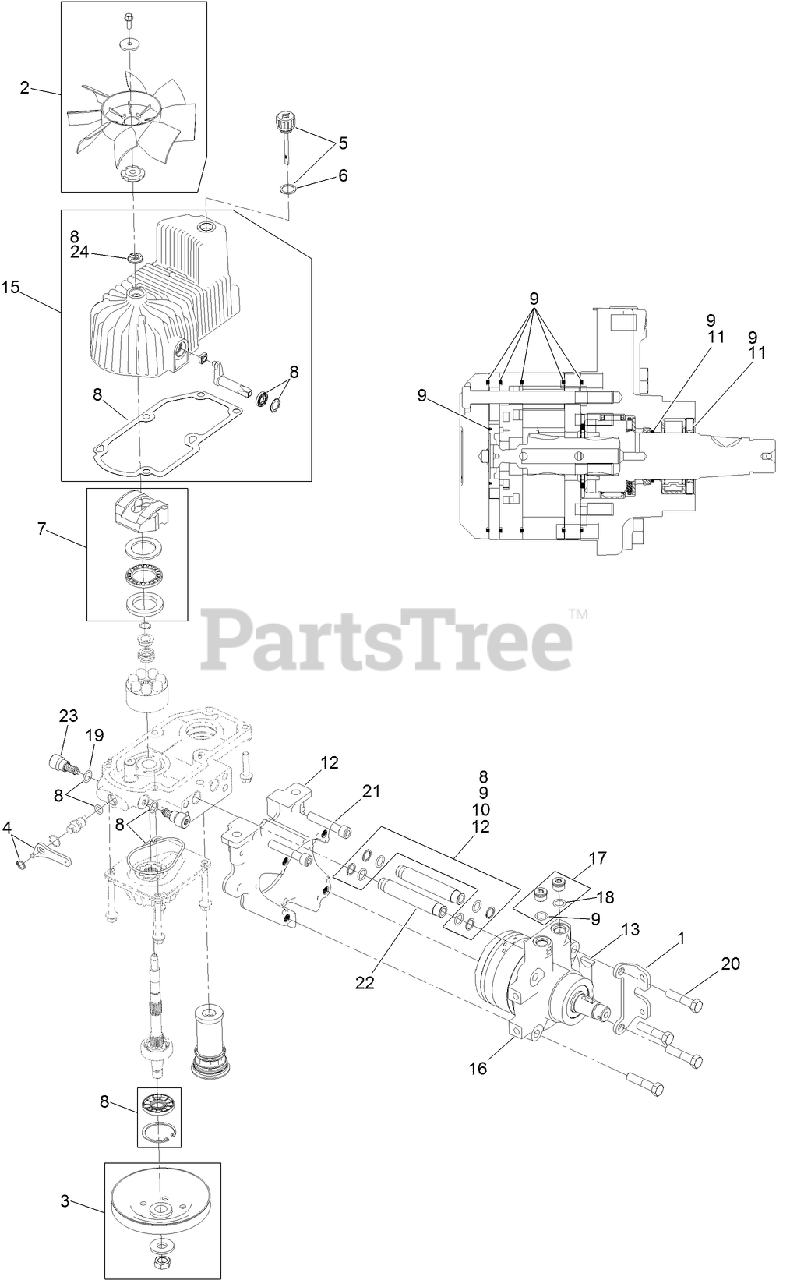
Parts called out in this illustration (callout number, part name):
1	MOUNT-SHOE, HORSE
2	FAN KIT
3	PULLEY KIT
4	HANDLE-BYPASS VALVE, HYDRO
5	DIPSTICK-HYDRO W/GASKET
6	GASKET-DIPSTICK, HYDRO
7	SWASH BLOCK KIT
8	PUMP SEAL KIT
9	MOTOR SEAL KIT
10	TUBE SEAL KIT
11	OUTPUT SHAFT SEAL KIT
12	NOSE CUP-UHT
13	KEY-WOODRUFF
15	Housing-RH
16	MOTOR-HYDRAULIC RH 240CC
17	MAGNETIC PLUGS SERVICE KIT
18	O-RING
19	O-RING-CHECK VALVE
20	SCREW HH
21	SCREW-HSH
22	HYDRAULIC TUBE KIT
23	SHOCK VALVE, 12CC HYDRO
24	SEAL-FAN DRIVE
